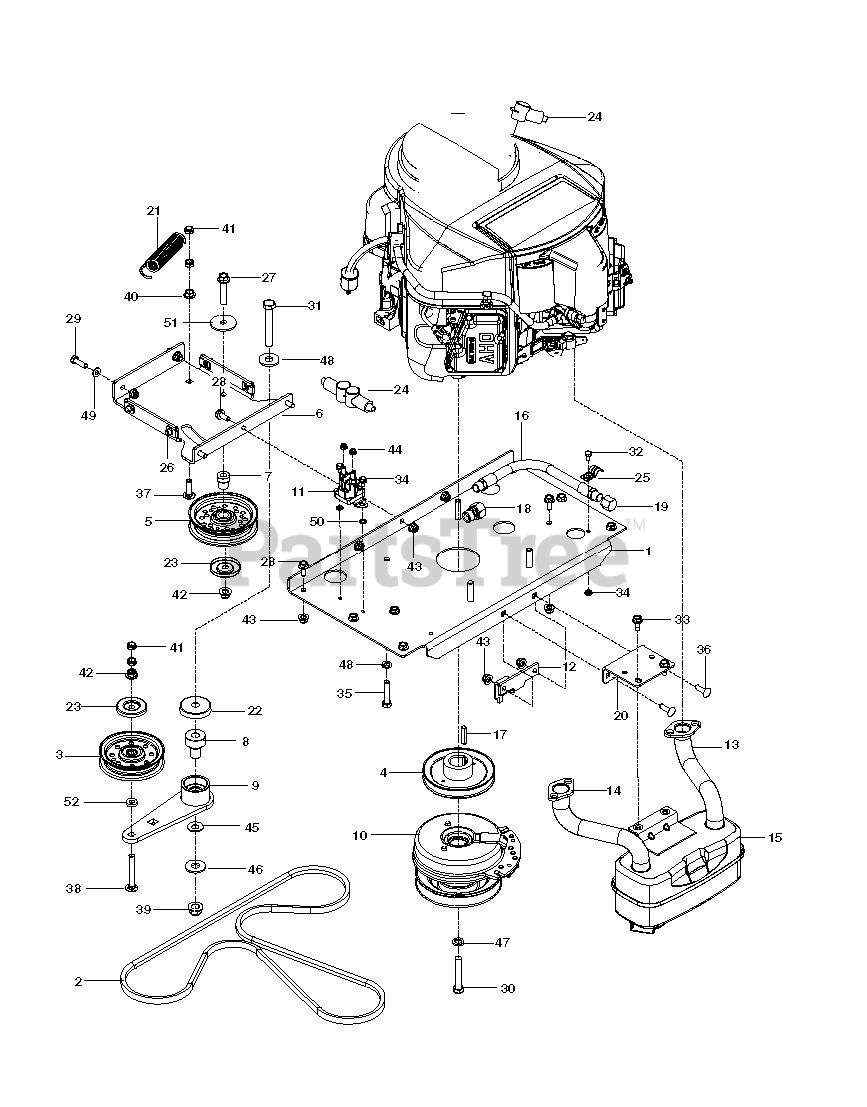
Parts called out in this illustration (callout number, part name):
1	PLATE, ENGINE W/DECALS
2	BELT, HYDRO, 3400
3	FLAT IDLER PULLEY
4	PULLEY, V, 1.125 BORE
5	IDLER PULLEY
6	PLATE, IDLER, BLK
7	PIVOT, IDLER
8	PIVOT, BEARING
9	ARM, IDLER, STEEL, W/BGS
10	CLUTCH 200 FT LB
12	STOP, CLUTCH, BLACK
13	TUBE.EXHAUST.LH.FR961/FR730
14	TUBE.EXHAUST.RH.FR961/FR730
15	MUFFLER ASM TWIN
16	OIL DRAIN HOSE
17	KEY, 1/4 SQ X 1 1/4
18	ADAPTER, OIL DRAIN
20	BRKT, MUFFLER, BLK
21	SPRING, PUMP
22	SHIELD, DUST
23	DUST SHIELD
26	U-CLIP 5/16-18 NUT RETAINER
27	HHFS 3/8-16 X 2.0 GD 5
28	HHFS 5/16-18 X 3/4
29	HCS 5/16C X 1
30	BOLT 7/16F X 2 1/2
31	HCS 1/2C X 3 1/4
32	HCS 1/4-20.
33	BOLT 5/16-18 X 3/4
34	HWST 1/4C X 3/8
35	BOLT, HCS 3/8-16X1-3/4
36	RHSSNB 5/16C X 1.0
37	RHSNB 3/8-16 X 1-1/4
38	RHSNB 3/8-16 X 2.75
39	NUT, 1/2-13 HEX FLG NYLOC ZD
40	NUT 3/8C WHIZ
41	NUT HEX 3/8-16 NYLON, THIN
42	NUT 3/8-16 HEX FLG NYLOC ZD
43	5/16-18 NYLOC FLANGE NUT
44	JAM NUT 1/4C (2 2 PW01)
45	CONTACT BELLSPR 1/2
46	WASH USS FLAT 1/2
47	WASHER 7/16 LOCK
48	SLW 3/8 STD
49	FLAT WASHER 5/16 SAE
50	WASHER 1/4 INT TOOTH
51	WASHER, 3/8 SPEC
52	WASHER 3/8 X 3/4 X .187 TK
